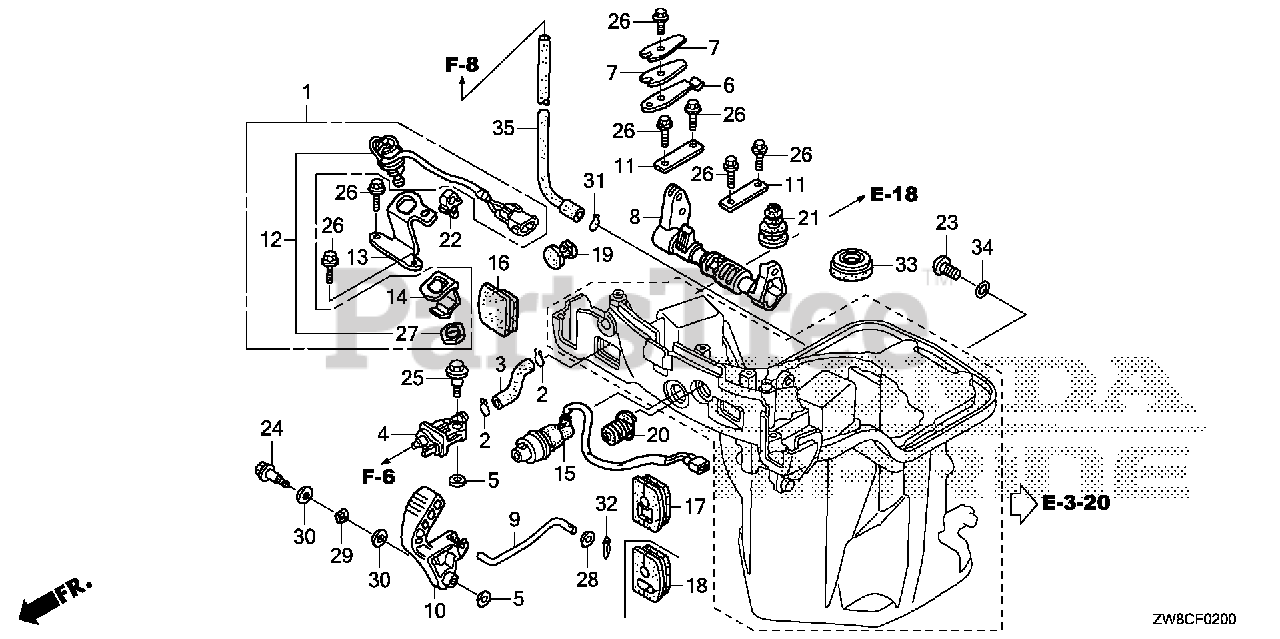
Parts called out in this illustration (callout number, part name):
1	SWITCH ASSY., NEUTRAL
2	CLIP, TUBE (ENGINE NO.)
3	TUBE A, FUEL (FKM)
4	CONNECTOR ASSY., FUEL (B)
5	WASHER, PIVOT
6	SPRING, CLICK
7	SPRING, CLICK ASSIST
8	SHAFT, SHIFT
10	LEVER, SHIFT
11	PLATE, SHIFT SHAFT
12	SWITCH ASSY., NEUTRAL
13	BRACKET, NEUTRAL SWITCH
14	PLATE, NEUTRAL SWITCH
15	LAMP ASSY., INDICATOR
16	GROMMET A, OIL CASE
18	GROMMET B, OIL CASE
19	GROMMET F, OIL CASE
20	GROMMET D, OIL CASE
21	GROMMET E, OIL CASE
22	CLIP, BRAKE PIPE (A) (FOR NEUTRAL SWITCH)
23	BOLT, OIL CHECK
24	BOLT, REVERSE LOCK
25	BOLT, SPECIAL (6X22) (CT200)
26	BOLT, FLANGE (5X12) (CT200)
27	NUT, HEX. (20MM) Use up to Frame SN 1300359.
28	WASHER, PLAIN (5MM)
29	WASHER, WAVE (10MM)
30	WASHER, PLAIN (9MM)
31	CLIP, TUBE (B10)
32	PIN, SPLIT (2.0)
33	SEAL, WATER (13X28X7) (ENGINE NO.)
34	O-RING (6.9X1.45)
35	TUBE, WATER CHECK
